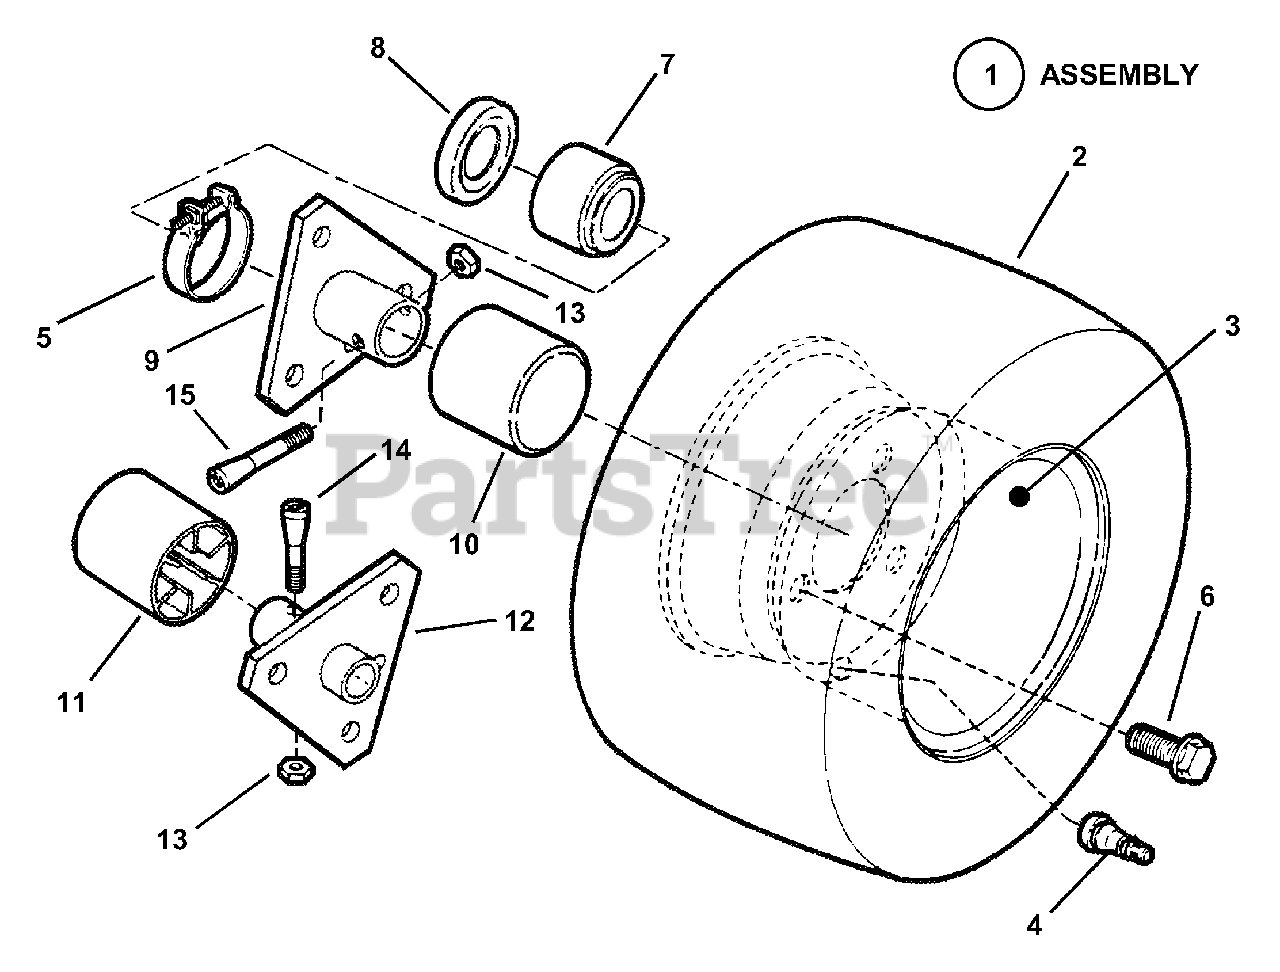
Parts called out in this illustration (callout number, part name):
1	ASSEMBLY, Rear Tire & Rim
2	TIRE, 16 x 6.50-8 (Kenda)
3	RIM, Ext. Wide
4	VALVE, Air (Snap-in)
5	CLAMP, Right Hand
6	BOLT, 1/2-20 x 3/4" Lug (Grade 5)
7	BOOT, Right Hand
8	SEAL, Oil
9	HUB, Rear Wheel (Right Hand)
10	CAP, Hub
11	CAP, Hub (Left Hand)
12	HUB, Rear Wheel (Left Hand)
13	NUT, 5/16-24 Hex Center Lock
14	BOLT, 5/16-24 x 1-5/8" Tapered (Left Hand)
15	BOLT, 5/16-24 x 2" Tapered (Right Hand)
